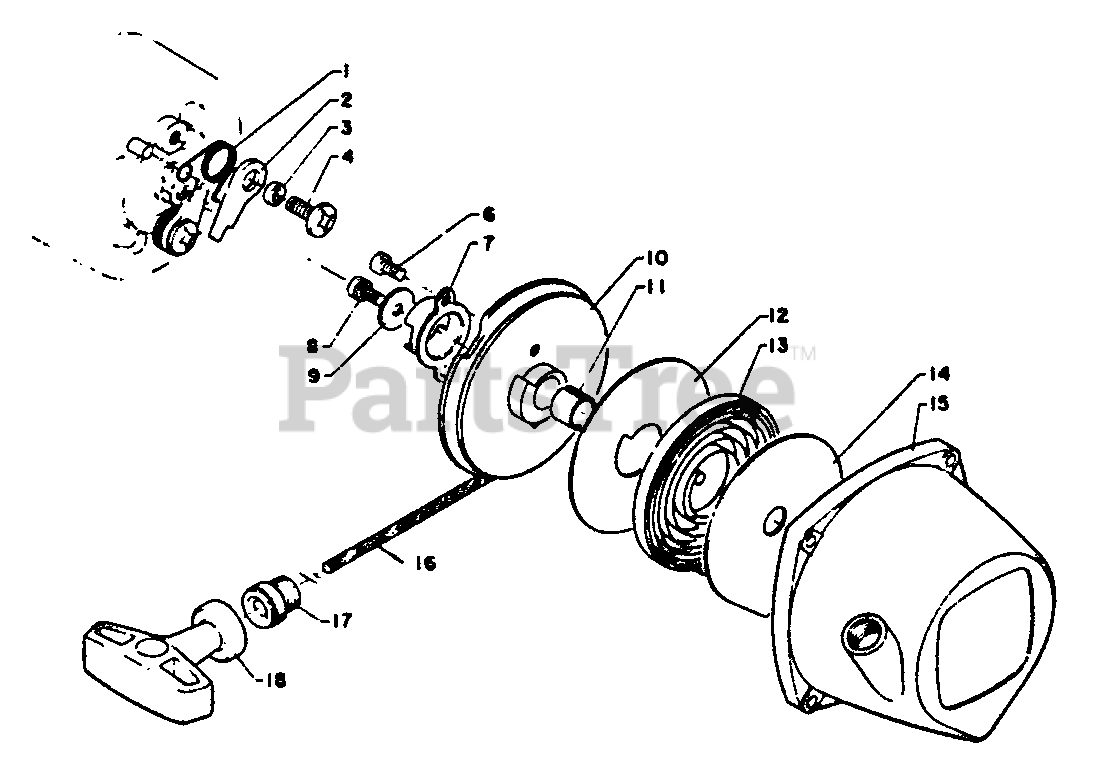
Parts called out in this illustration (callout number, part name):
1	SPRING, RETURN
2	PAWL, STARTER
3	SPACER 5.2×8×2.1
4	SCREW
6	SCREW 4×8
7	PAWL CATCHER
8	SCREW 4×8
9	WASHER 4.1×15.5×1T
10	REEL, ROPE
12	PLATE, STARTER
13	SPRING, RECOIL
14	PLATE, STARTER
15	CASE, STARTER
16	ROPE, STARTER 3.5×850
17	GUIDE, ROPE
